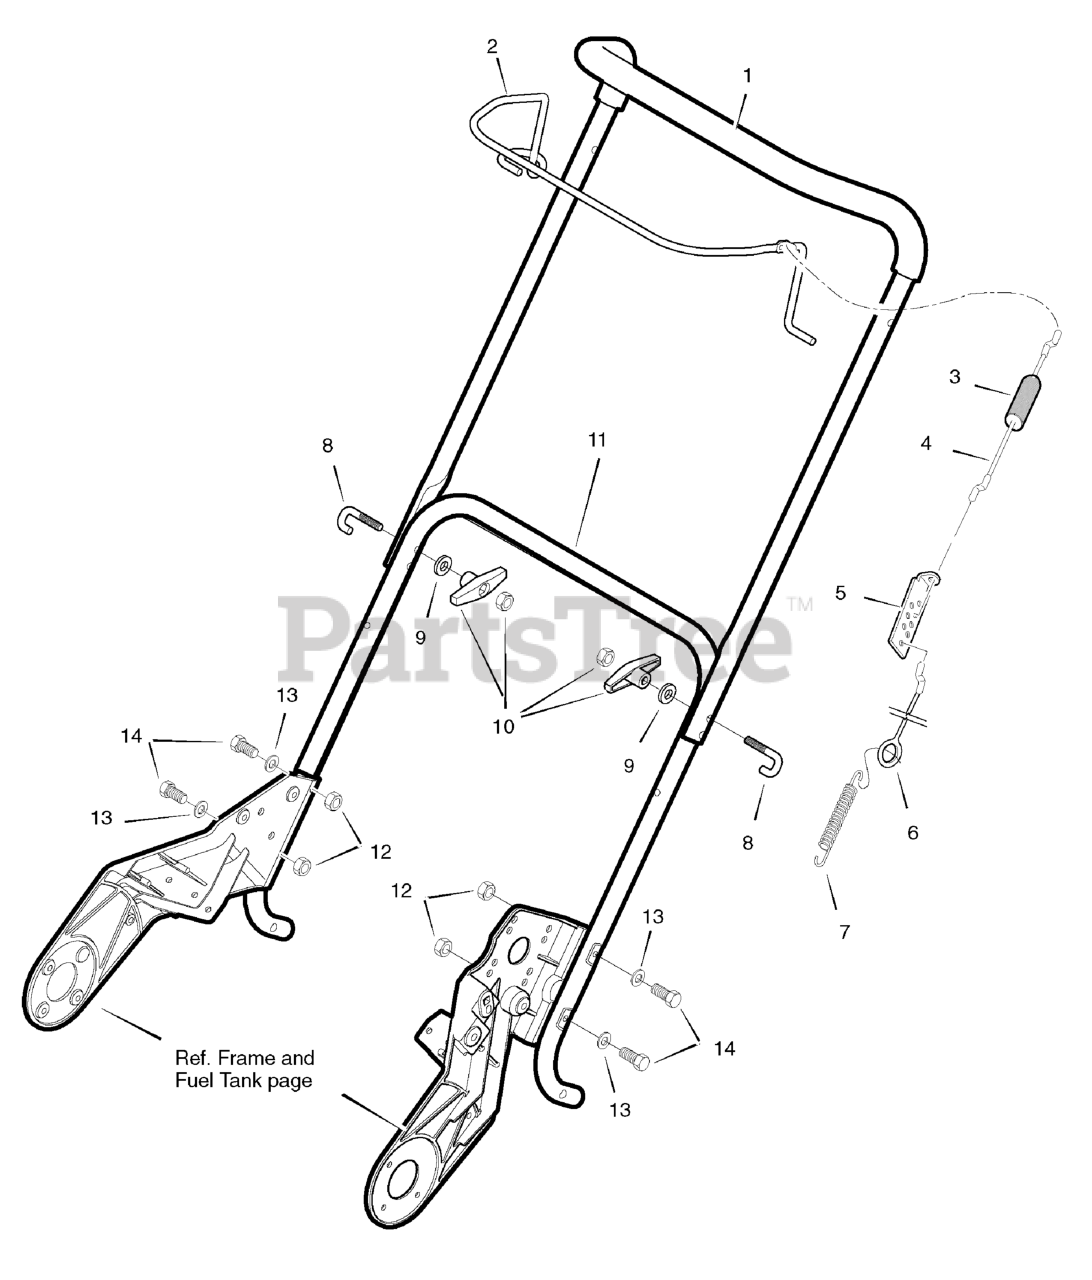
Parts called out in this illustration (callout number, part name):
1	HANDLE & GRIP ASSEMBLY
2	CONTROL, Bail
3	BOOT, Clutch Spring
4	CABLE, Upper Control
5	BRACKET, Control Adjust
6	CABLE, Lower Control
7	SPRING
8	Bolt, "U"
9	WASHER
10	KNOB
11	HANDLE, Lower
12	NUT
13	WASHER
14	SCREW, 1/4 - 20 x 1-1/4
